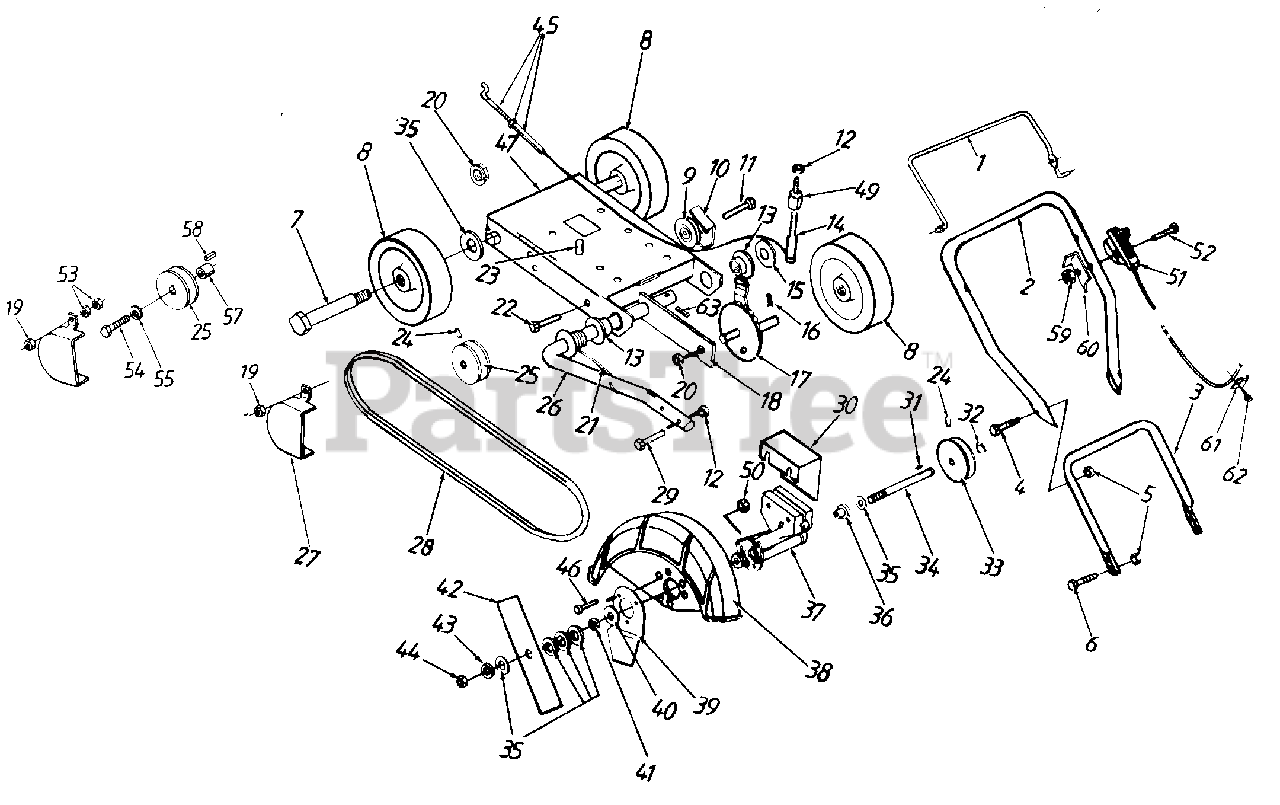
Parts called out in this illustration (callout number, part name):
1	Lever-Depth Control
2	Upper Handb
3	Lower Handle
4	Hex Bolt 5/16-18 x 1.5
5	Hex L-Nut 5/16-18 Thd.
6	Hex Bolt 5/16-18 x .625
7	Wheel Bolt
8	Wheel - 6"
9	Idler Pulley
10	Bracket-Idler Pulley
11	Bolt
12	Hex L-Nut 5/16-18 Thd.
13	Bushing
14	Arrn-Pivot Rod
15	Flat Washer 5/8-1.D.
16	Cotter Pin 1/8 x 3/4
17	Adjustor Assembly
18	Arrn-Front Wheel
19	Hex L-Nut 1/4-20 Thd.
20	Hex Keps L-Nut 3/8-16 Thd.
21	Spring-Cutterhead
22	Hex Bolt 5/16-18 x 1"
23	Engine Bolt
24	Locking Set Scr. 5/16-18
25	Engine Pulley
26	Rod-CuKerhead
27	Belt Guard
28	V-Belt
29	Hex Bolt 5/16-18 x 1.5"
30	Belt Guard
31	Woodruff Key
32	Retaining Ring
33	Pulley-Cutterhead
34	Shaft-Cutterhead
35	Flat Washer .063- Thk.
36	Bushing-Cutterhead
37	Housing-Cutterhead Shaft
38	Blade Guard
39	Edge Guide
40	Flat Washer .035-Thk.
41	HeavvHexJamNul3/8-24
42	9 Replacement Blade
43	Spring L-Wash. 3/8 I.D.
44	Hex Nut 3/8 24 Thd.
45	Cable-Depth Control
46	Hex Wash. Hd. Scr. #10-24
47	Base-Edger Frame
49	Spacer-Pivot Arm
50	Nylok Nut #10-24
51	Throttle Control
52	Hex Bolt 1/4-20 x 1.75
53	Hex Nut 1/4-20 Thd. t536)
54	Hex Bolt 3/8-24 x 1.75
55	Bell-Wash. 3/8" I.D.
57	Spacer
58	Sq. Key 3/16" x .75"
59	Hex L-Nut 1/4-20 Thd.
60	Stop Bracket
61	Cable Clamp
62	Hex Tap Scr. #8 x 3/8
63	Spiral Pin
